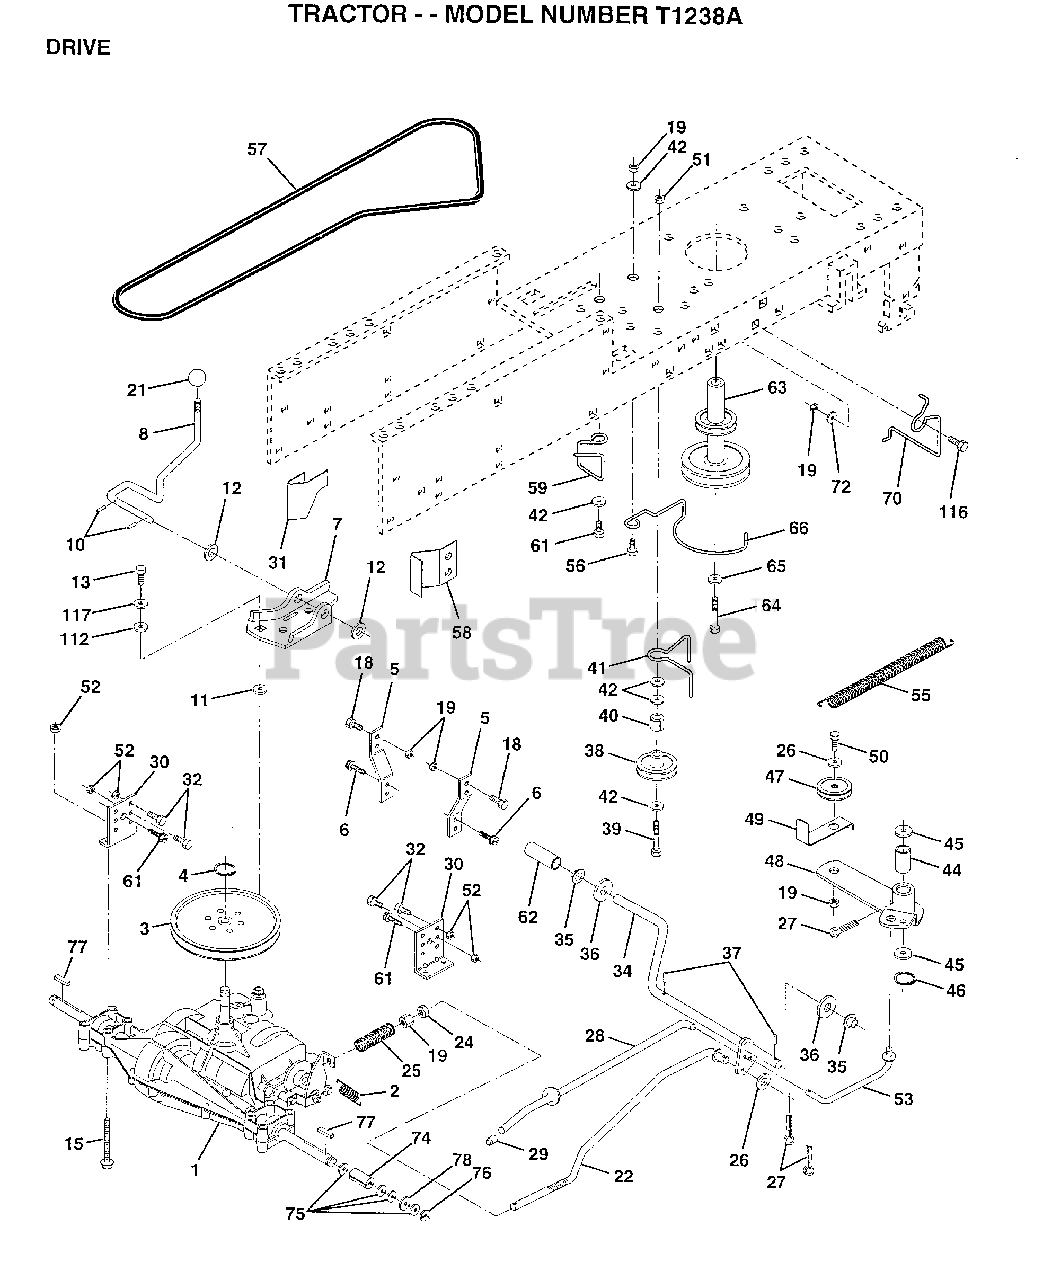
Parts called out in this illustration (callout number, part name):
2	SPRING.BRAKE.RETU
3	PULLEY TRANS
5	STRAP TORQUE
6	SCREW
8	SHIFT ROD
10	PIN COTTER 1/8
11	WASH-SHFT PLT LT
12	WASHER
13	BOLT.1/4-28.W/PAT
14	LOCKWASHER
15	BOLT.HX.FLG.5/16
18	BOLT
19	NUT
21	KNOB T (1/2-HOLE)
22	BRAKE ROD
24	NUT
25	SPRING ROD LT
26	WASHER
27	COTTER PIN
28	ROD.BRAKE.PARK.LT
28	"KEEPER,BELT RH T"
29	PLUNGER CAP T
30	TRANSAXLE MTG BKT
31	"KEEPER,BELT LH T"
32	BOLT
34	SHAFT.PEDAL.FOOT
35	NYLON BEARING
36	WASHER LT
38	PULLEY.IDLER.FLAT
39	BOLT
40	SPACER T
41	BELT KEEPER LT
42	WASHER
44	"LY, BEARING"
45	WASHER LT
46	KLIP RING
48	ARM IDLER
49	RETAIN BELT
53	"LINK, CLUTCH T"
55	"SPRING, RETURN LT"
59	KEEPER BELT CNTSP
61	SCREW
62	PEDAL COVER T
63	PULLEY.ENGINE
64	BOLT
65	LOCKWASHER
66	KEEPER.BELT.ENG.L
70	KEEPER BELT ENG
72	WASHER
74	SPACER LT
75	WASHER
76	E-RING LT
77	SQUARE KEY
78	WASHER
112	WASHER LT
116	BOLT RDHD 3/8-16
